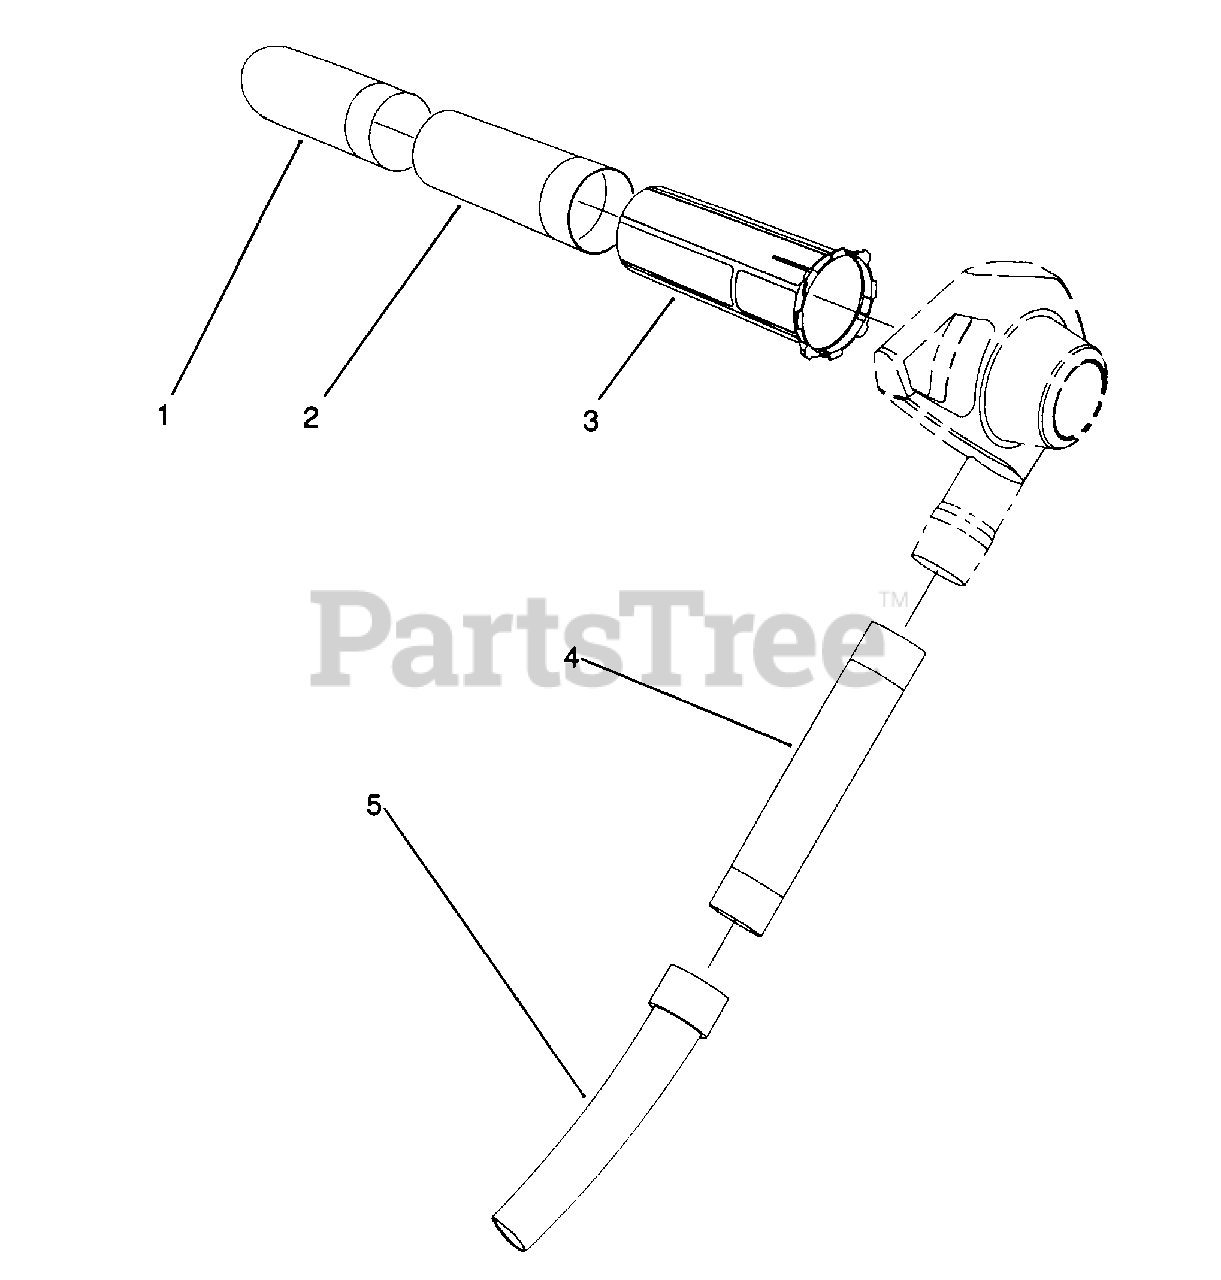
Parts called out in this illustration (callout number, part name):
1	Vac Tube-Lower
2	Vac Tube-Middle
3	Vac Tube-Upper
4	Tube-Blower
